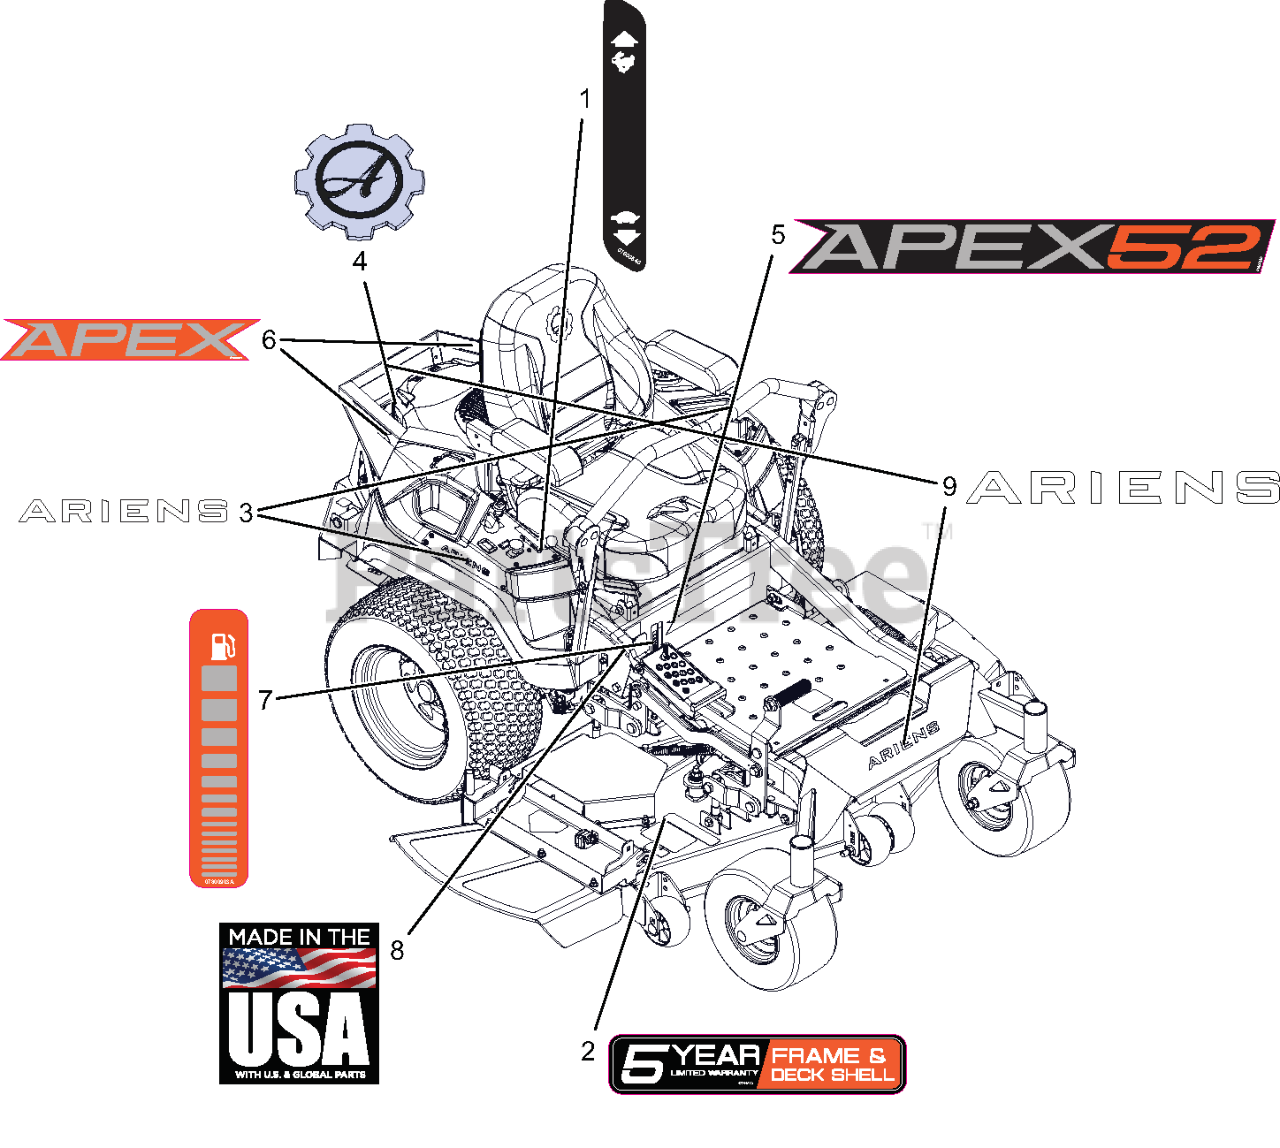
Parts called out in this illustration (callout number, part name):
1	DECAL, DASH
2	DECAL, DECK - 5 YEAR ARIENS
3	DECAL, ARIENS 6.00"
4	DECAL, ARIENS - GEAR BADGE (THK)
5	DECAL, KICKPLATE - ARIENS APEX 52
6	DECAL, APEX FENDER
7	DECAL, FUEL LEVEL - ARIENS APEX
8	DECAL, MADE IN USA
9	DECAL, ARIENS - BADGE
